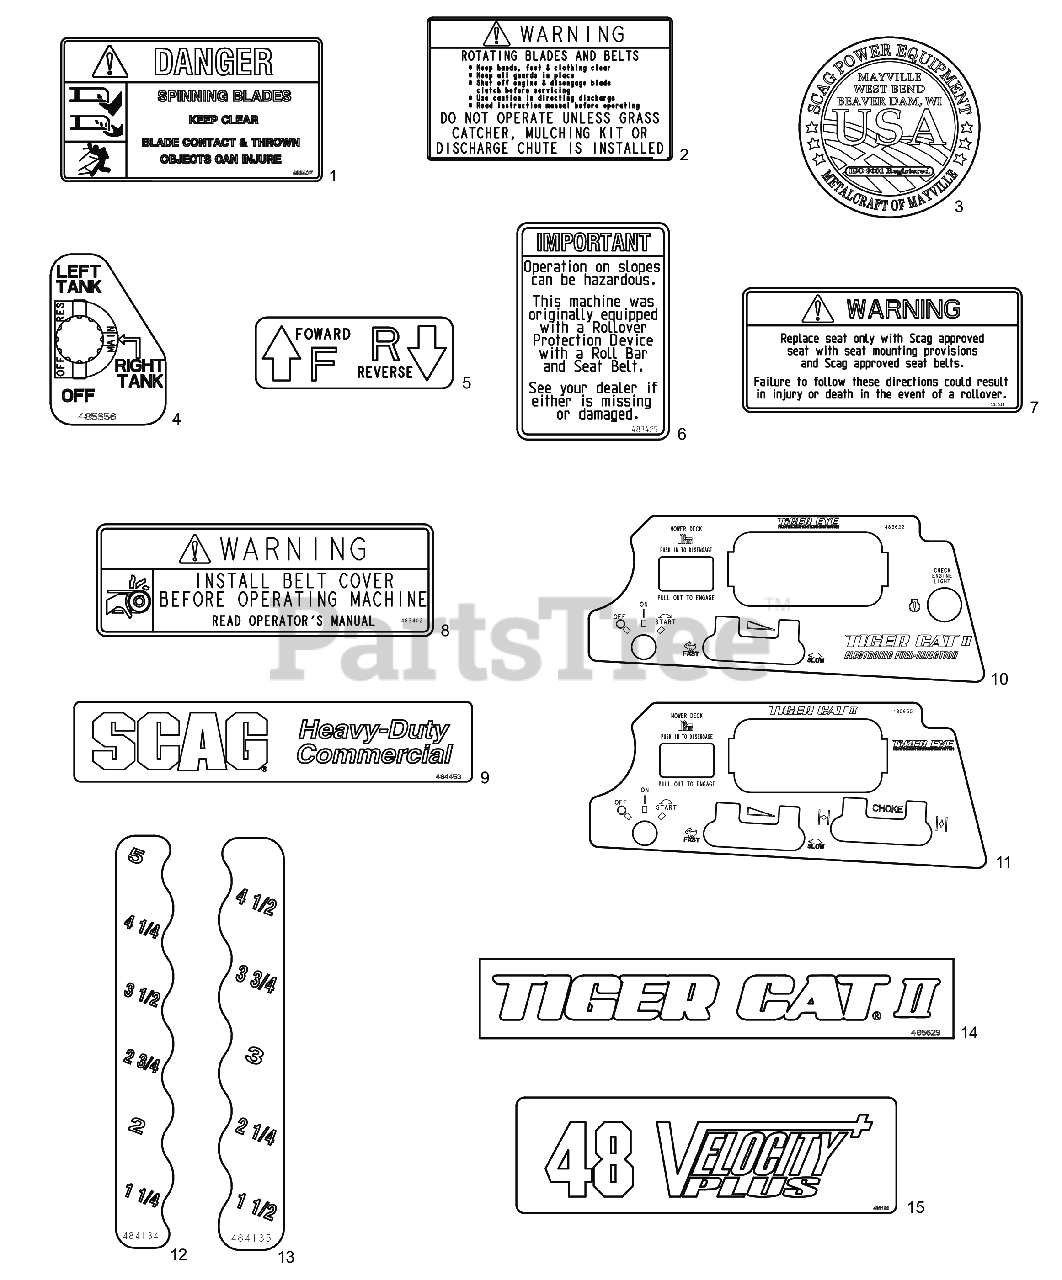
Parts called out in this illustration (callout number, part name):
1	Decal, Danger-Spinning Blades
2	Decal, Warning - Rotating Blades
3	Decal, Metalcraft - USA
4	Decal, Fuel Valve Position
5	Decal, Traction Control
6	Decal, ROPS
7	Decal, Seat Replacement
8	Decal, Warning - Belt Cover
9	Decal, Scag Heavy Duty Commercial
10	Decal, Instrument Panel - EFI
10	Decal, Instrument Panel - Kawasaki EFI
11	Decal, Instrument Panel
12	Decal, Deck Height - LH
13	Decal, Deck Height - RH
14	Decal, Tiger CatII
15	DECAL, VELOCITY PLUS - 48
